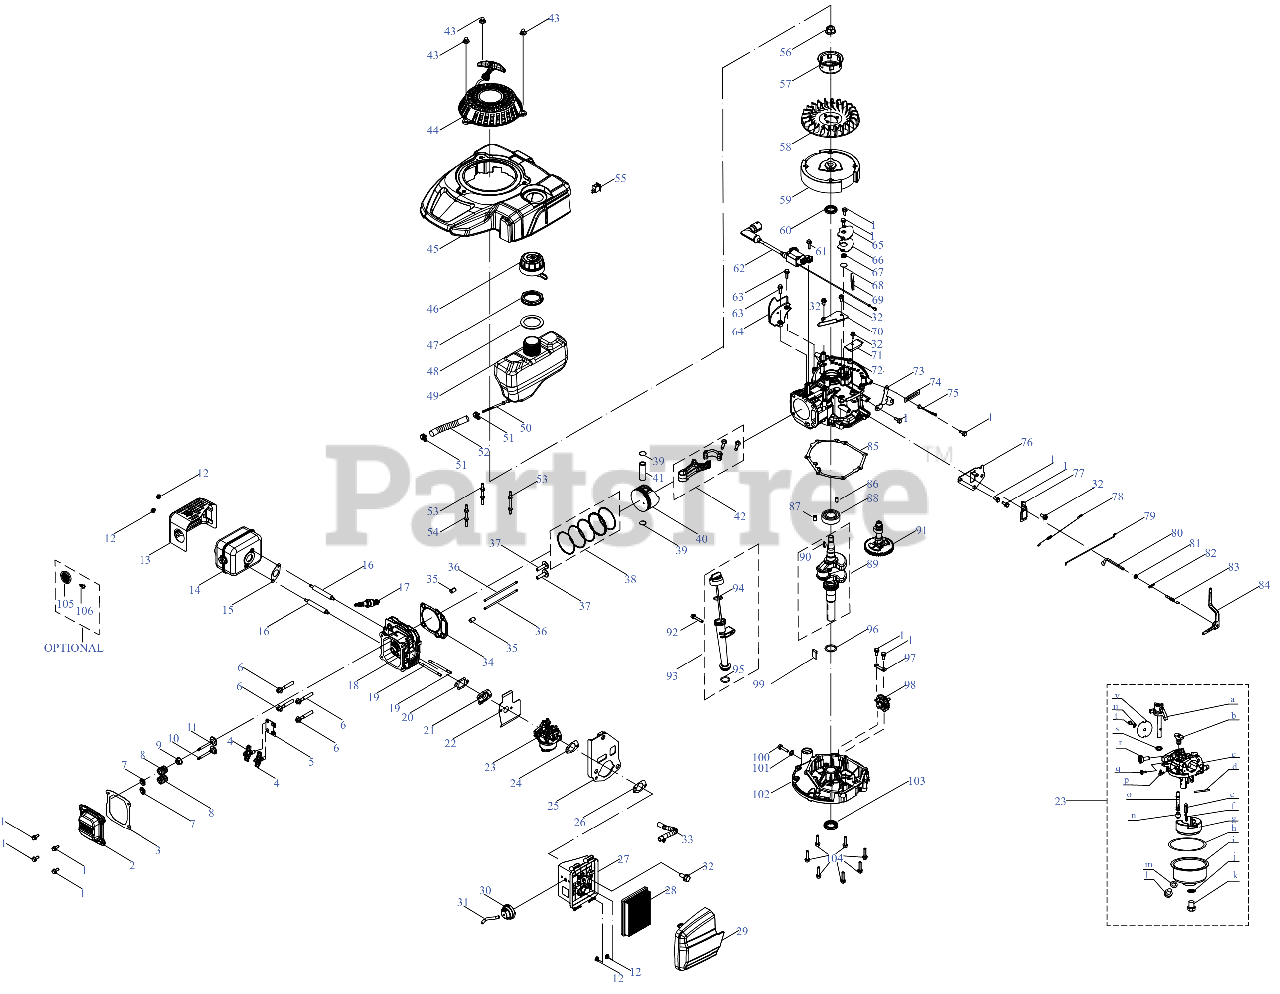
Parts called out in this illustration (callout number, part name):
1	BOLT M6-1 x 14 GR8.8
2	VALVE COVER
3	VALVE COVER GASKET
4	ROCKER ARM ASSEMBLY
5	PUSH ROD GUIDE
6	BOLT-M8 x 54
7	VALVE SPRING RETAINER
8	VALVE SPRING
9	INTAKE VALVE SEAL
10	EXHAUST VALVE
11	INTAKE VALVE
12	HEX NUT
13	MUFFLER SHIELD
14	MUFFLER
15	MUFFLER GASKET
16	STUD M6-1 x 95
17	SPARK PLUG
18	CYLINDER HEAD
19	CARBURETOR STUD-M6 x 87
20	CARBURETOR GASKET
21	CARBURETOR INSULATOR
22	CARBURETOR GASKET
23	CARBURETOR
24	AIR FILTER BASE GASKET
25	AIR FILTER BRACKET
26	CHOKE TEMP CONTROL BRACKET GSKT
27	AIR FILTER BASE WITH PRIMER
28	AIR FILTER
28	Cub Cadet AIR FILTER
28	Genuine Factory Parts AIR FILTER
29	AIR FILTER COVER
30	VENTED PRIMER ASSEMBLY
31	PRIMER HOSE
32	BOLT M6-1 x 12 GR8.8
33	BREATHER HOSE ASSEMBLY
34	CYLINDER HEAD GASKET
35	DOWEL PIN
36	PUSH ROD
37	TAPPET
38	PISTON RING SET
39	SNAP RING-PISTON PIN
40	PISTON
41	PISTON PIN
42	CONNECTING ROD ASSEMBLY
43	ACORN NUT
44	RECOIL STARTER ASSEMBLY
45	ENGINE SHROUD ASSEMBLY
46	FUEL CAP W/TETHER
47	FUEL TANK NUT
48	FUEL TANK UPPER GROMMET
49	FUEL TANK
50	FUEL FILTER
50	Genuine Factory Parts FUEL FILTER
51	HOSE CLAMP
52	FUEL HOSE
53	STARTER/SHROUD REAR STUD
54	STARTER/SHROUD FRONT STUD
55	IGNITION SWITCH
56	FLYWHEEL NUT
57	STARTER CUP
58	COOLING FAN
59	FLYWHEEL
60	CRANKSHAFT SEAL
61	BOLT M6-1 x 20 GR8.8
62	IGNITION COIL
63	BOLT M6-1 x 25 GR8.8
64	ENGINE BRAKE COVER PLATE
65	BREATHER COVER PLATE
66	BREATHER GASKET
67	BREATHER VALVE SPRING
68	BREATHER VALVE
69	BREATHER SCREEN
70	AIR VANE COVER PLATE
71	GROUND COVER PLATE
72	CRANKCASE
73	CHOKE CONTROL BRACKET
74	FLEXIBLE CLAMP
75	GROUND WIRE
76	COMPONENT BRACKET
77	GOVERNOR SHIELD
78	THROTTLE LINKAGE SPRING
79	THROTTLE LINKAGE
80	GOVERNOR ARM SHAFT
81	GOVERNOR SEAL
82	COTTER PIN
83	GOVERNOR SPRING
84	GOVERNOR ARM ASSEMBLY
85	CRANKCASE COVER GASKET
86	DOWEL PIN
87	DOWEL PIN
88	BEARING
89	CRANKSHAFT ASSEMBLY
90	FLYWHEEL KEY
91	CAMSHAFT ASSEMBLY
92	BOLT M6-1 x 35 GR8.8
93	OIL DIPSTICK ASSEMBLY
94	O-RING
95	O-RING
96	THRUST WASHER
97	GOVERNOR GEAR MOUNTING PLATE
98	GOVERNOR GEAR/SHAFT ASSEMBLY
99	OIL RETURN SEAL
100	OIL DRAIN PLUG
101	WASHER
102	CRANKCASE COVER
103	LOWER CRANKSHAFT SEAL
104	BOLT-M6-1 x 28 GR8.8
105	SPARK ARRESTOR
106	SCREW M3.5 x 9.5
